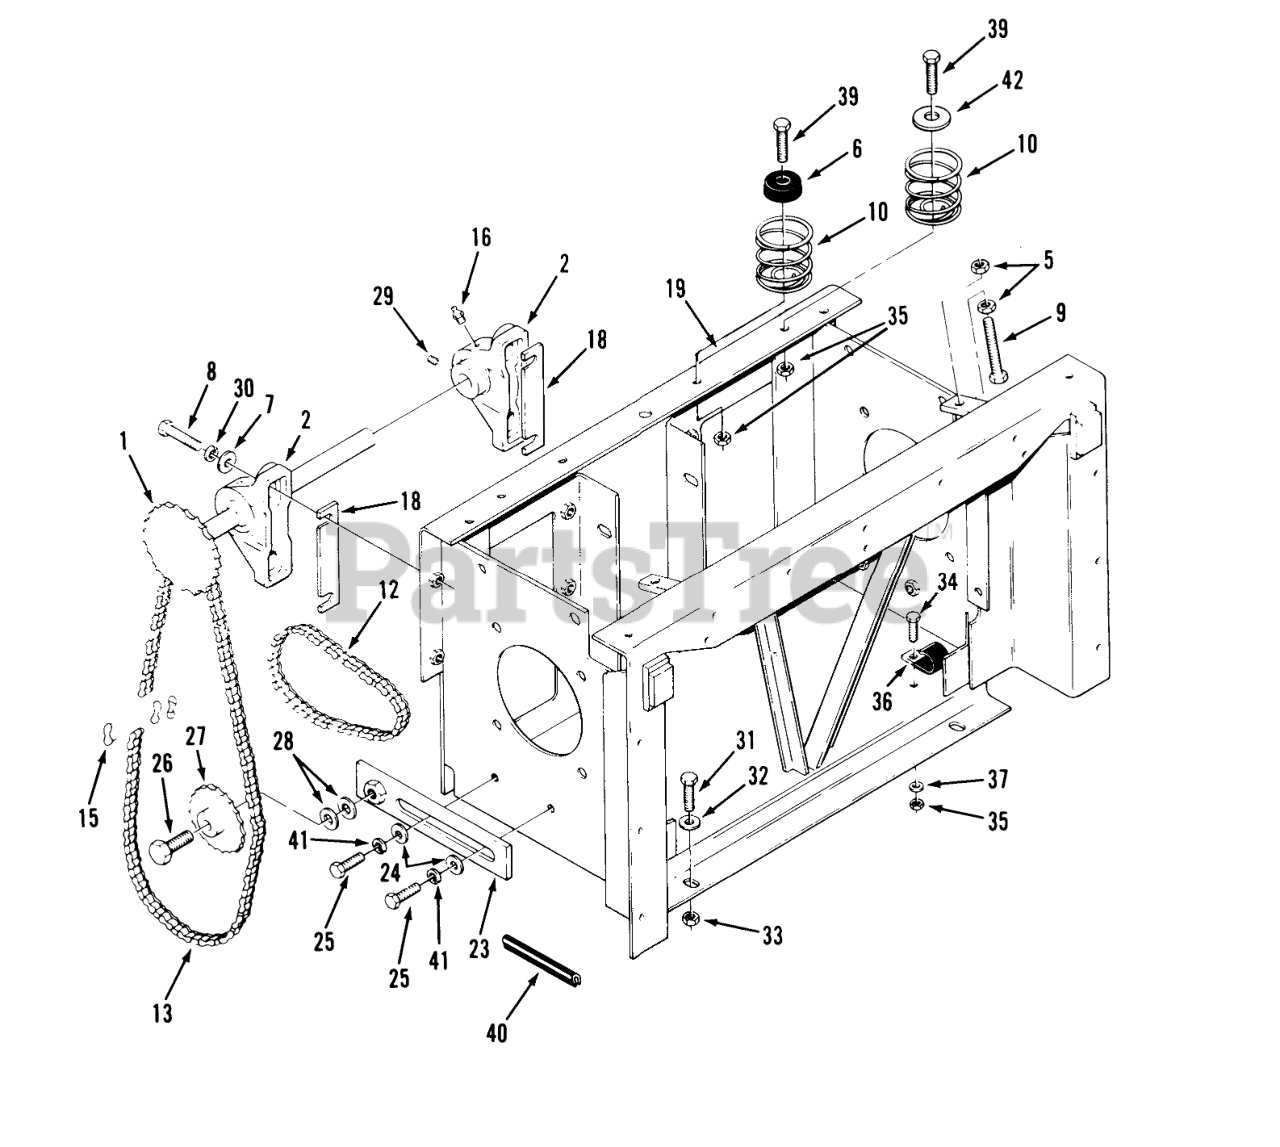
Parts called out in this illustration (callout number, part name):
1	ASSY-JACKSHAFT PLT
2	Bearing-Pillow Block (Incl. Items 16 & 29)
5	NUT-HEX
6	BUMPER
7	WASHER-FLAT
8	SCREW-HH
9	SCREW-HH
10	SPRING-SEAT NYLON
12	CHAIN-#50 PRIMARY
13	ROLLER-CHAIN #50 SEC
15	CONNECTING LINK
16	Fitting-Grease
18	SHIM-PILLOW BLOCK
19	WLDMT-FRAME TRANS B
23	ASSY-CHAIN TENSIO B
24	WASHER
25	SCREW-HH
26	SCREW-HH
27	IDLER SPROCKET 20288
28	WASHER-FLAT
29	SCREW-HSH
30	WASHER-LOCK
31	SCREW-HH
32	WASHER-FLAT
33	NUT-LOCK, NI
34	SCREW-HH
35	NUT-LOCK, NI
36	CLIP
37	WASHER-PLAIN
39	SCREW-HH
40	EDGE TRIM
41	WASHER-LOCK
42	WASHER
